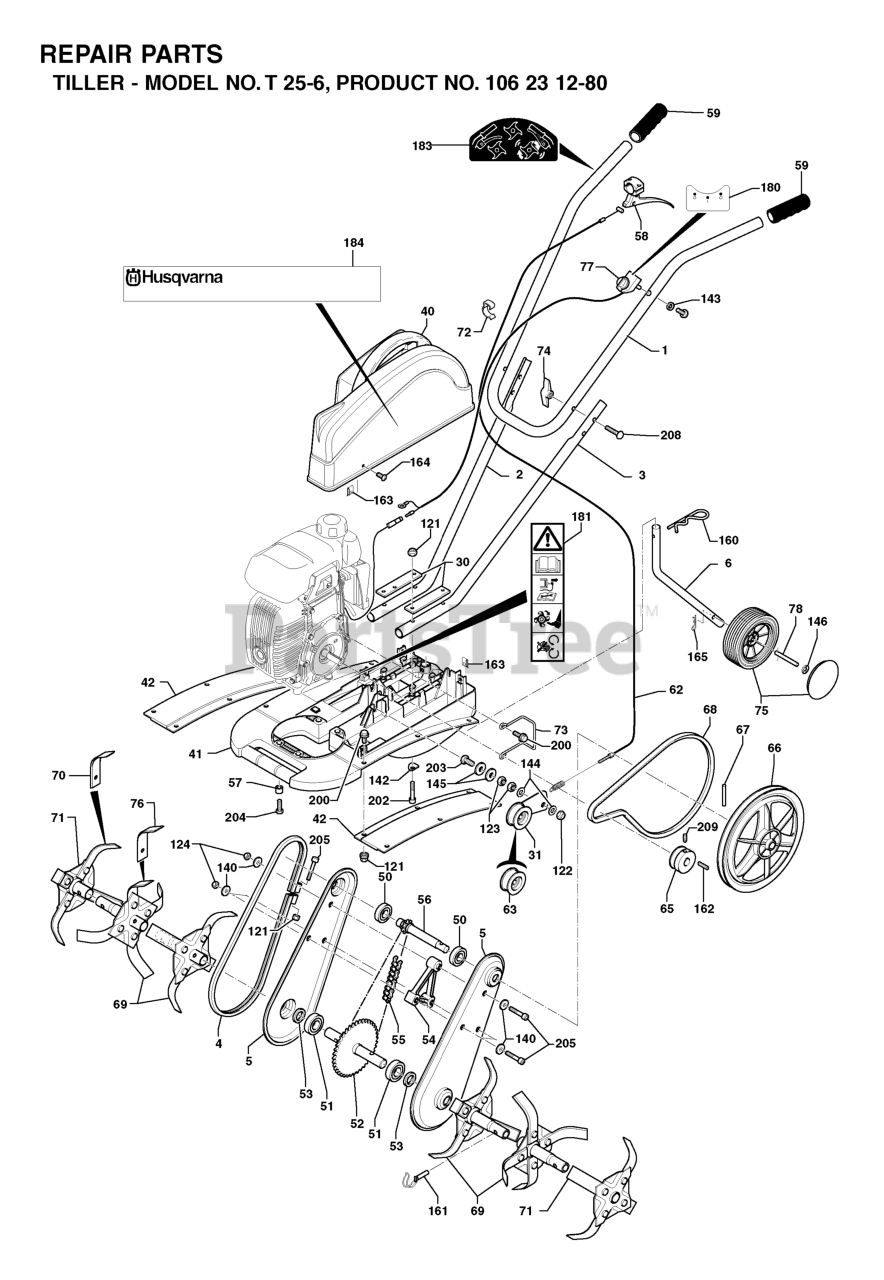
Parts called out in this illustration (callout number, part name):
121	Blocking nut M 6 Z
144	WASHER
165	COTTER PIN
